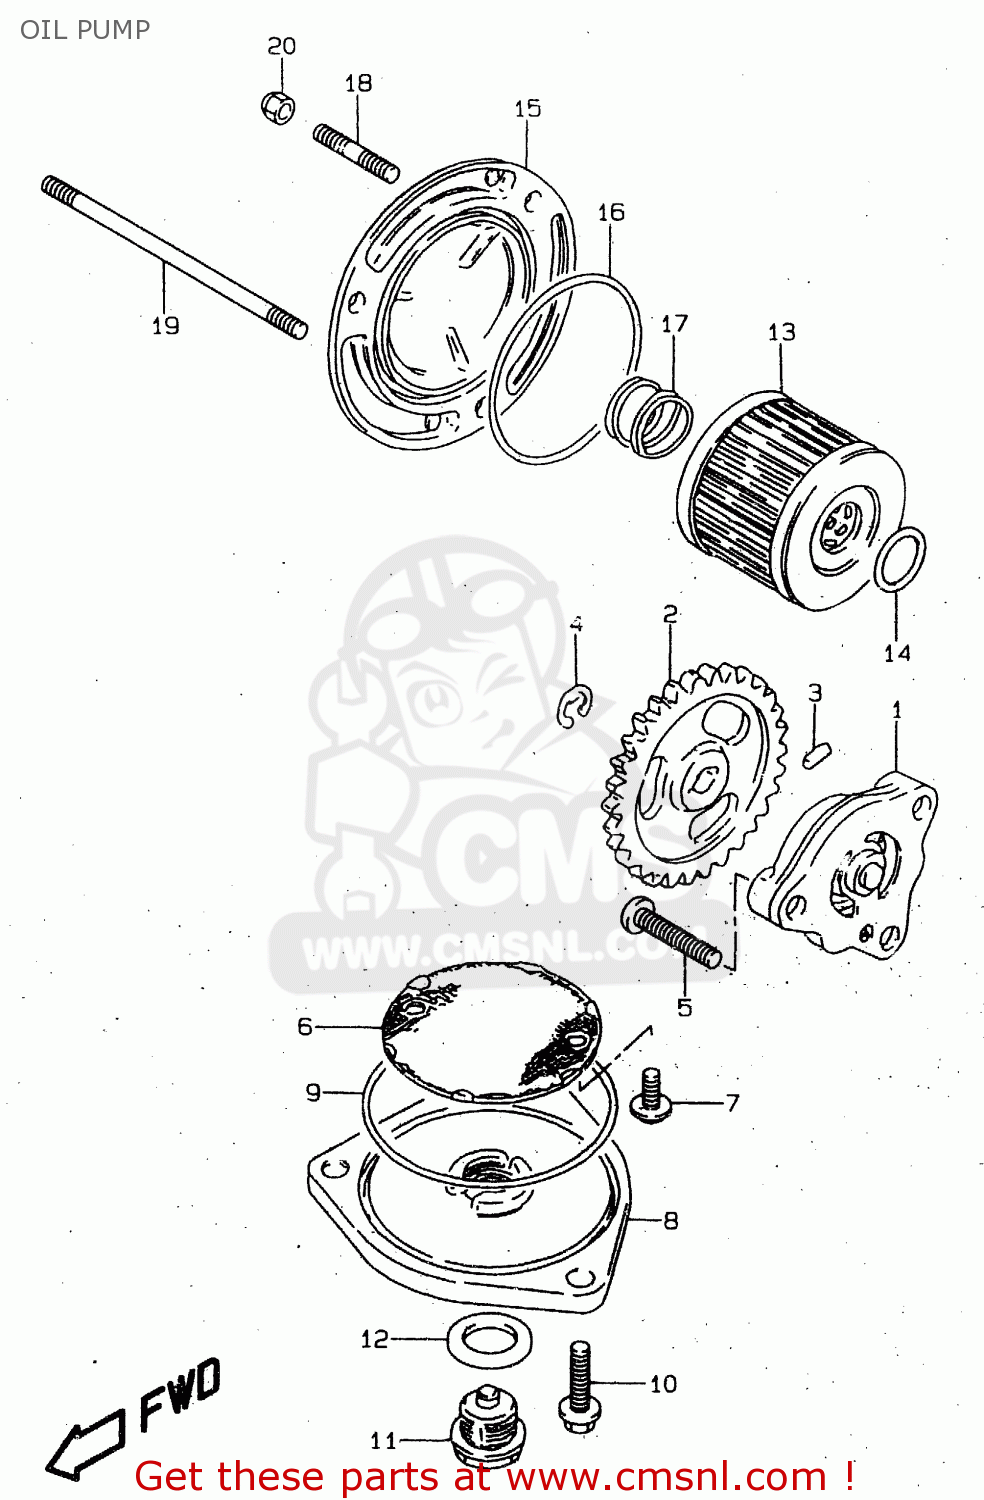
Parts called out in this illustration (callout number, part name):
1	PUMP ASSY,ENGINE OIL
2	GEAR,ENG OIL PUMP DRIVEN(NT:30
3	PIN(2.5X11.8)
4	E.RING
5	SCREW
6	STRAINER,ENGINE OIL
7	SCREW
8	CAP,OIL STRAINER
9	O RING(D:2.4,ID:60.5)
10	SCREW
11	PLUG
12	GASKET(13.8X18.8X4.8) (NAS)
13	FILTER ASSY,ENGINE OIL
14	O RING(D:1.9,ID:13)
15	CAP,OIL FILTER
16	O RING(D:2.4,ID:52.6)
17	SPRING
18	STUD 6X12
19	STUD BOLT, 6X8
20	NUT
